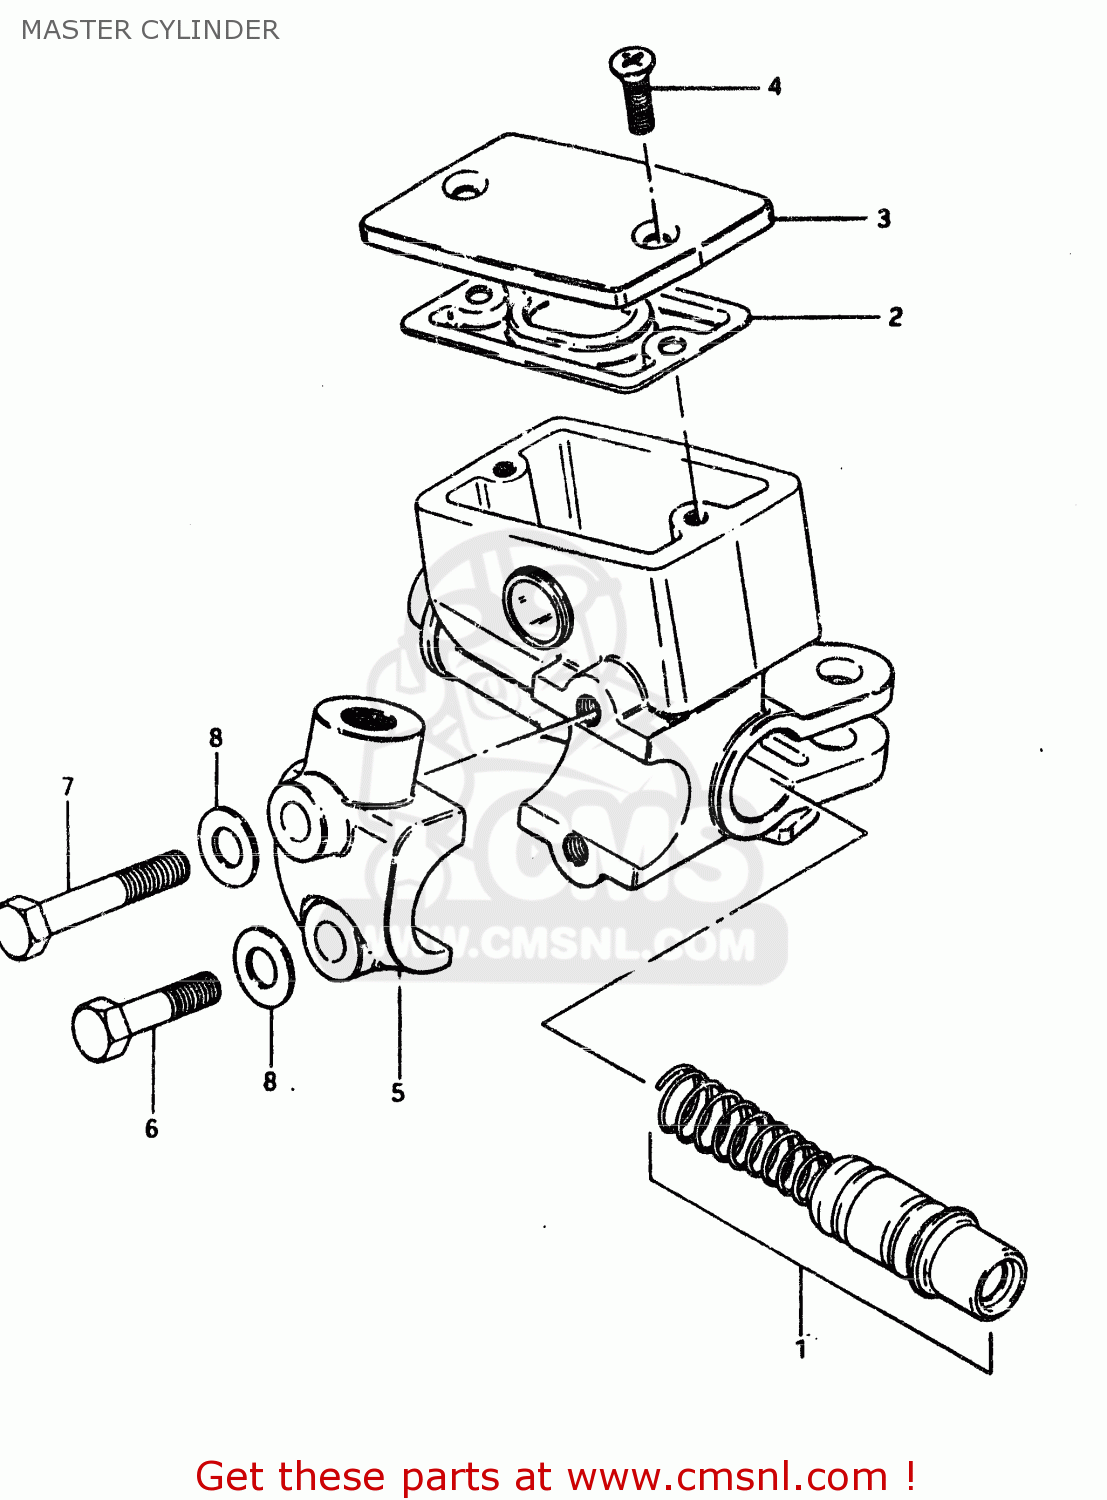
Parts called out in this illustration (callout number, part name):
1	PISTON & CUP SET
2	3
3	CAP
4	SCREW
5	HOLDER
6	BOLT
7	BOLT 6X40
8	LOCK WASHER
